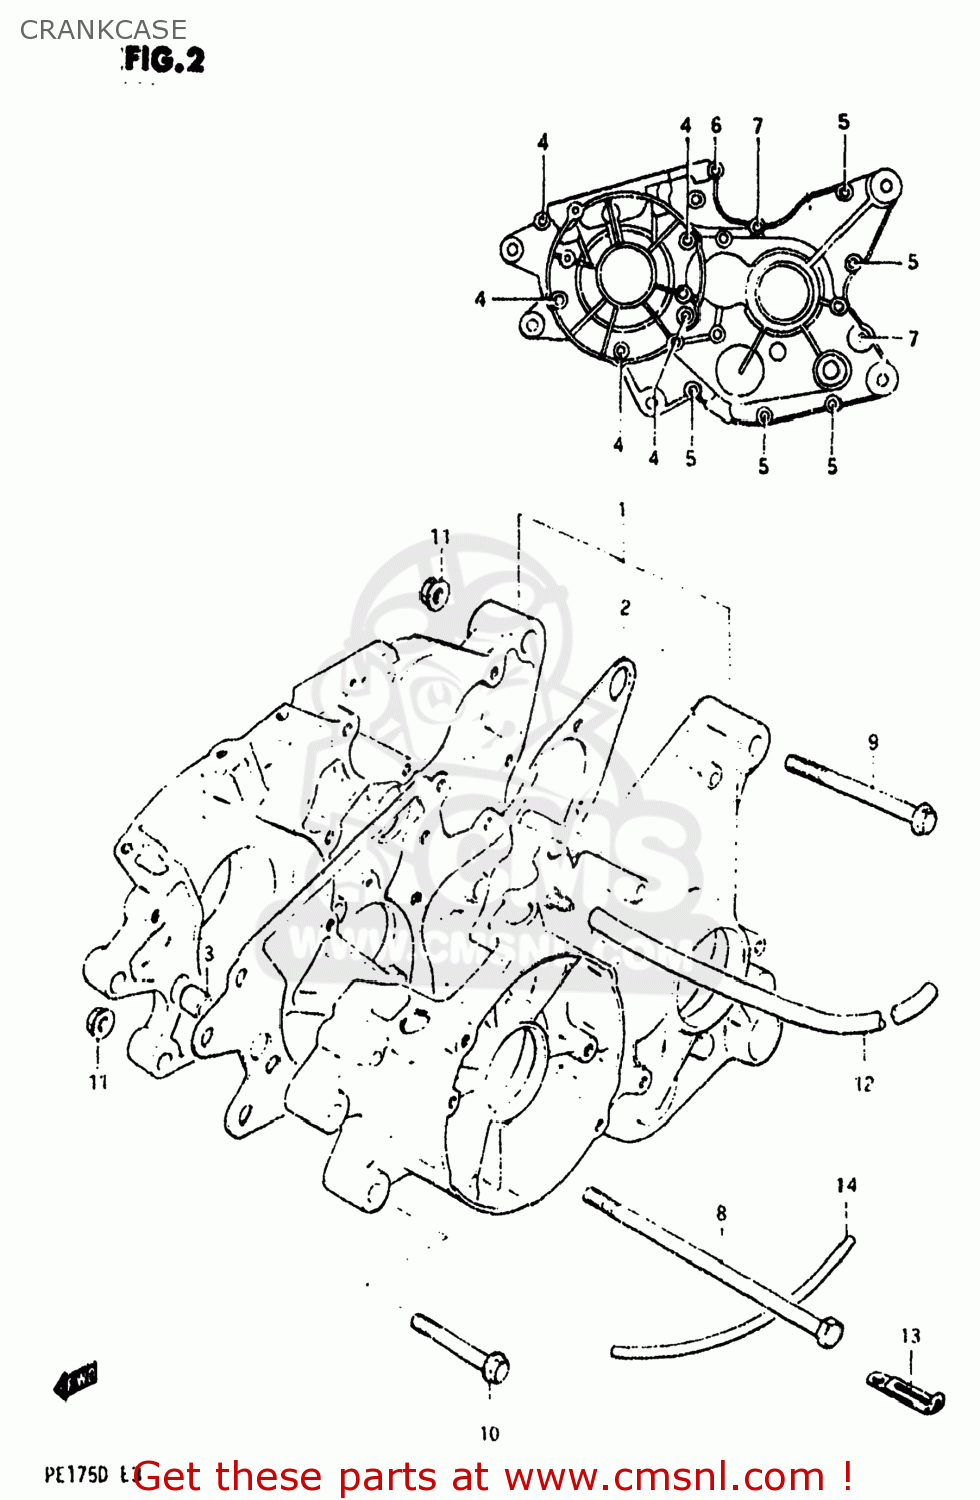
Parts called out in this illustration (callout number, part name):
1	CRANKCASE SET
2	GASKET,CRANKCASE
3	PIN
4	SCREW (6X45)
5	SCREW
6	SCREW
7	SCREW 6X60
8	BOLT 8X175
9	BOLT (8X95)
10	BOLT 8X65
11	NUT
12	HOSE,FUEL
13	CLAMP
14	HOSE
